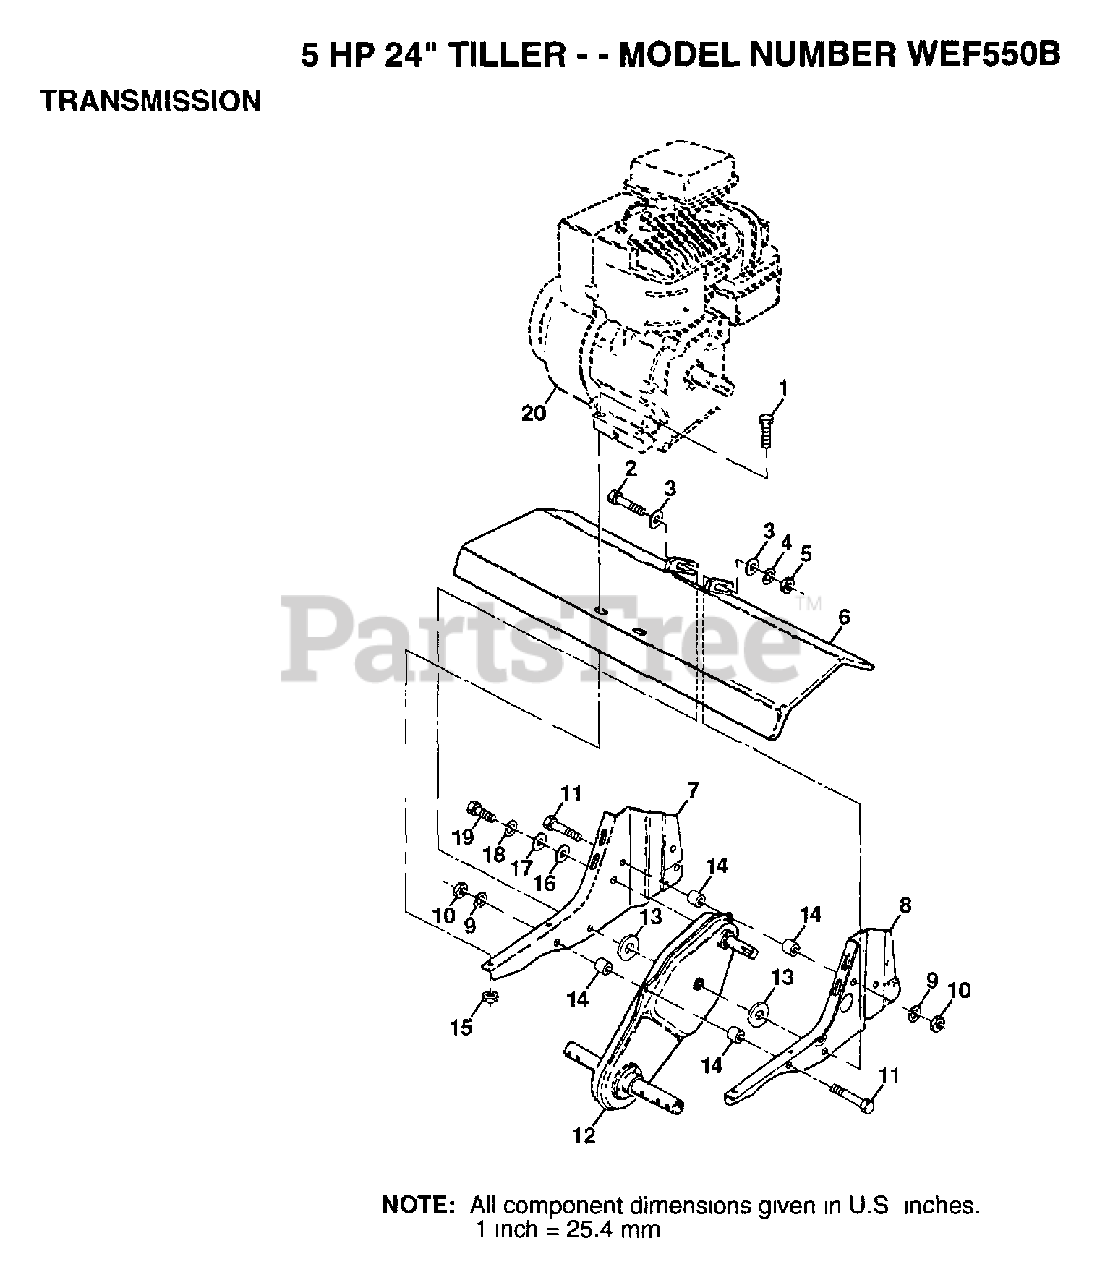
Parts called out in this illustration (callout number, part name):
1	BOLT.HEX.5/16-1.5
2	BOLT.3/8-24X3.75
3	WASHER
4	LOCKWASHER
5	GRIPCO NUT
8	BRACKET.ENG.LH.
9	LOCKWASHER
10	NUT.HEX.5/16-18
14	SPLIT SPACER RT
16	WASHER
17	WASHER
18	LOCKWASHER
19	BOLT
